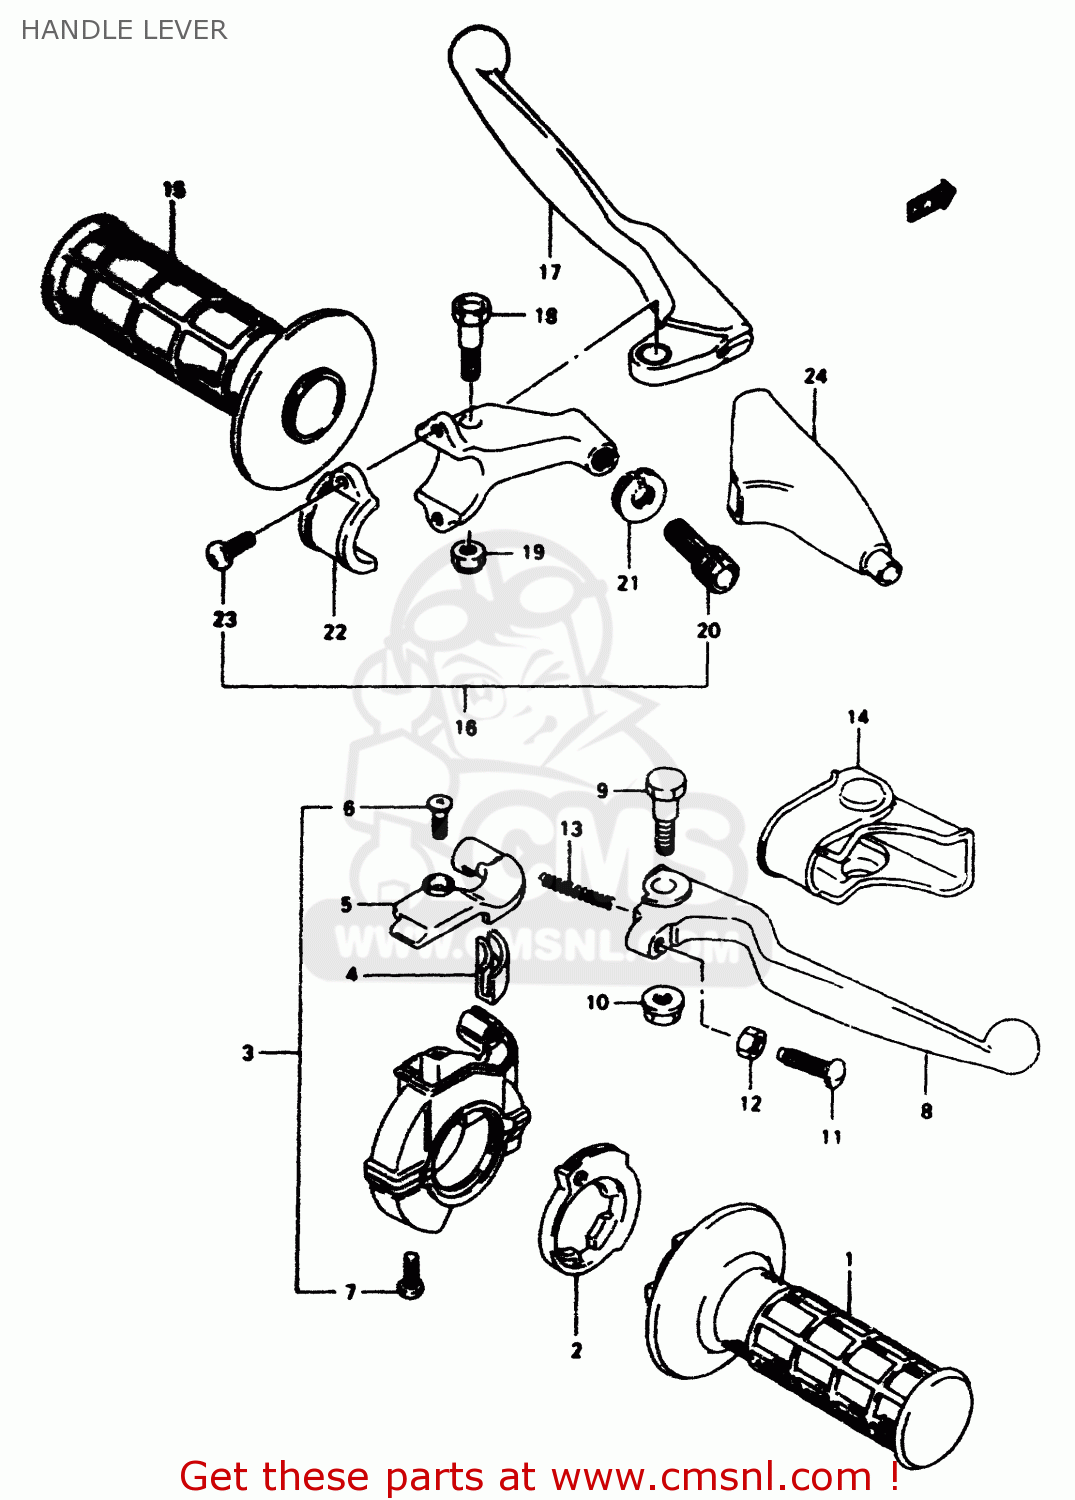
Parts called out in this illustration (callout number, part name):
1	GRIP,THROTTLE
2	ROTOR,THROTTLE GRIP
3	CASE ASSY,THROTTLE
4	GUIDE PIECE,THROTTLE
5	COVER,THROTTLE CASE
6	SCREW,UPPER
7	SCREW
8	LEVER,BRAKE
9	BOLT,BRAKE LEVER
10	NUT,BRAKE LEVER
11	BOLT,ADJUST
12	NUT
13	SPRING,RETURN
14	COVER,BRAKE LEVER
15	GRIP,L
16	LEVER ASSY,CLUTCH
17	LEVER,CLUTCH
18	BOLT,LEVER
19	NUT 6MM
20	ADJUSTER,CABLE
21	NUT,CABLE ADJUSTER
22	BRACKET,CLUTCH LEVER HOLDER
23	SCREW(5X14)
24	HOLDER,CLUTCH LEVER
25	COVER,CLUTCH LEVER
